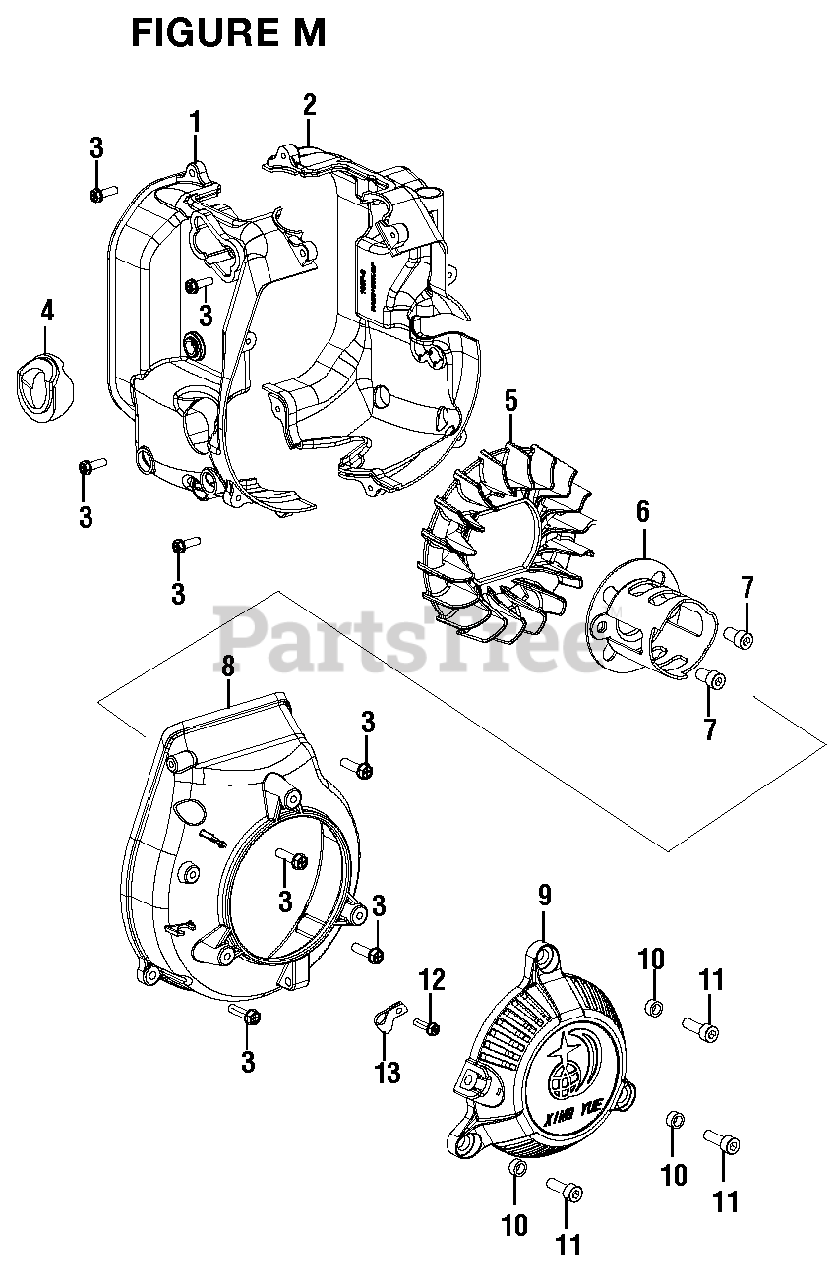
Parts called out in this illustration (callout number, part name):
1	Air Guide Sleeve (A)
2	Air Guide Sleeve (B)
3	Screw (M4.8 x 16 mm)
7	Screw (M6 x 10 mm, Hex Hd.)
9	Recoil Starter
10	Recoil Starter Bushing
11	Bolt (M5 x 16 mm, Flange Hex Hd.)
12	Screw (M4.2 x 10 mm)
13	Ignition Coil Wires Clamp
